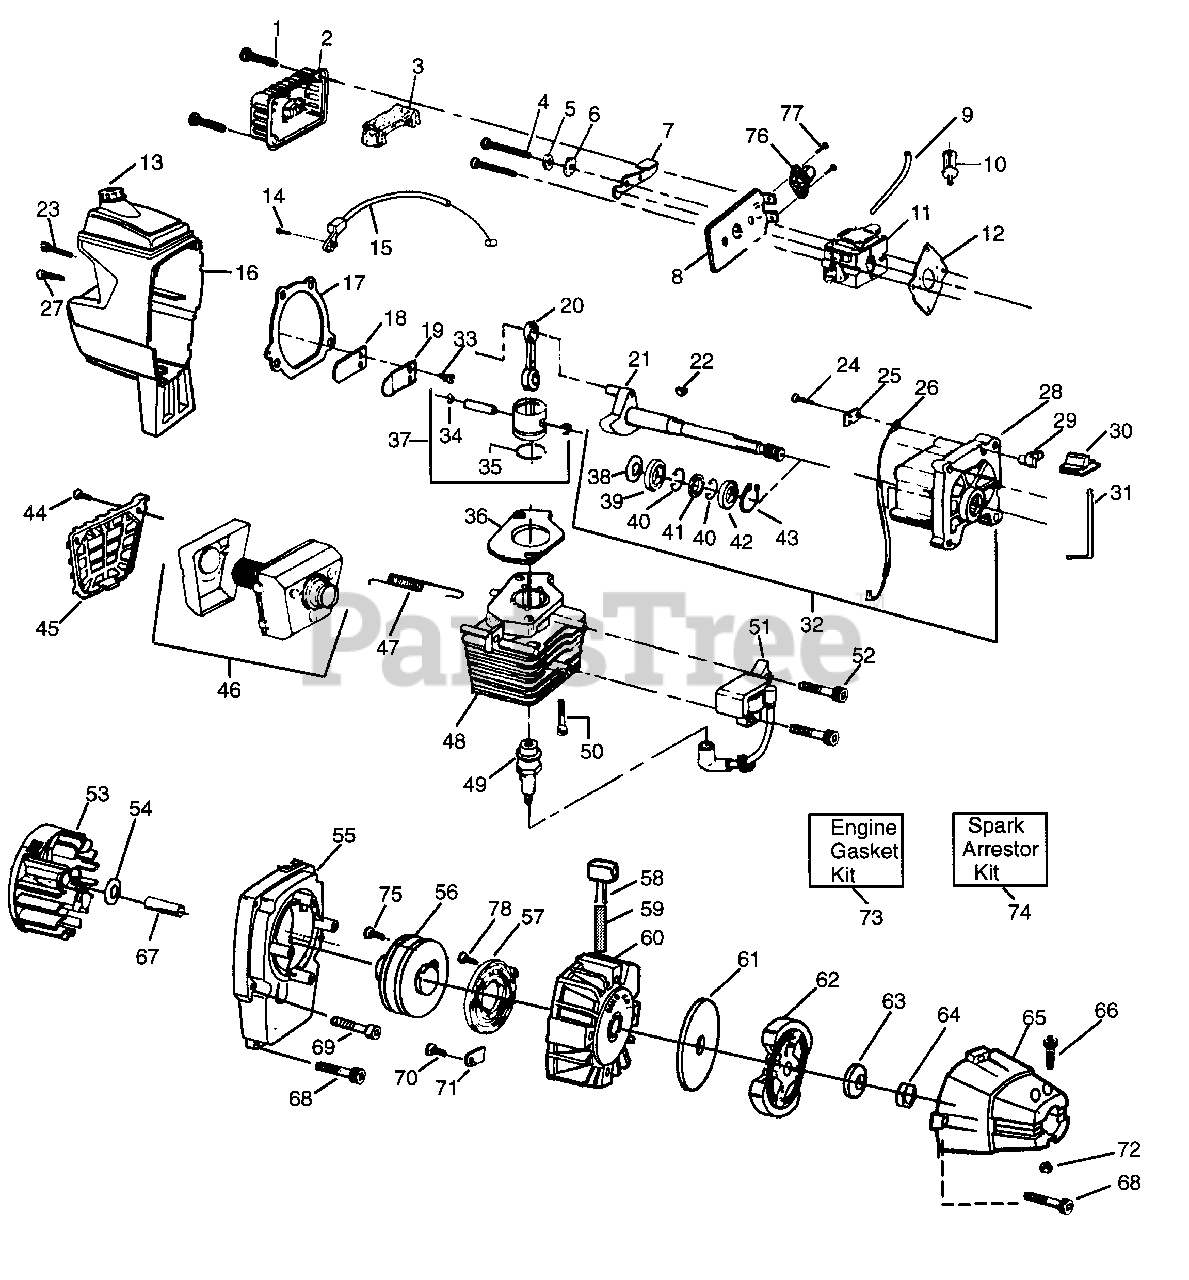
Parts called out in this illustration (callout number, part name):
2	Air Filter Cover
3	Air Filter
6	Wave Washer
7	Choke Shutter
8	XT85 & XT85T Type 1
8	XT85T Type 2 & 3
9	Fuel Line
9	Return Line Type 2 & 3
10	Fuel Pick-up Ass'y.
11	XT85 & XT85T Type 1 (WA-199)
11	XT85T Type 2 & 3 (WT-298A)
12	Carburetor Gasket
13	Fuel Cap Ass'y.
15	XT85 & XT85T Type 1
15	XT85T Type 2 & 3
16	XT85 & XT85T Type 1
16	XT85T Type 2 & 3
19	Reed Stop
20	Connecting Rod Ass'y. (Inc. Bearings)
21	Crankshaft Ass'y. See Service Ref. 1
22	Flywheel Key
25	Switch Insulator
26	Lead Wire
28	Crankcase Ass'y. (Inc.#39-42)
29	Switch Ramp
30	Switch Button
31	Switch Spring
32	Crankcase & Crankshaft Ass'y. (Inc.21,28, 39-43)
34	Piston Pin Retainer
35	Piston Ring
36	Cylinder Gasket
37	Piston Kit (Inc. 34, 35 & pin)
39	Inner Bearing
40	Retaining Ring
41	Crankshaft Seal
42	Outer Bearing
43	Crankshaft Retaining Ring
45	Muffler Guard
46	Muffler Kit
47	Muffler Spring
48	Cylinder
49	Type 1 & 2 (CJ-14)
49	Type 3 (RCJ-8Y)
51	Ignition Module Kit
52	Screw
53	Flywheel Ass'y.
54	Washer
55	Fan Housing
56	Starter Pulley Kit (Inc. 75)
57	Starter Spring
58	Starter Handle
59	Rope Kit
60	Pulley Housing Ass'y.
61	Clutch Washer
62	Clutch Ass'y. Kit
65	Clutch Housing
71	Pulley Retainer
73	Engine Gasket Kit
74	Spark Arrestor Kit
75	Screw-Rope Retaining
76	Primer Bulb Ass'y. XT85T Type 2 & 3
77	Screw-Primer XT85T Type 2 & 3
78	Screw-Starter Spring Type 3
